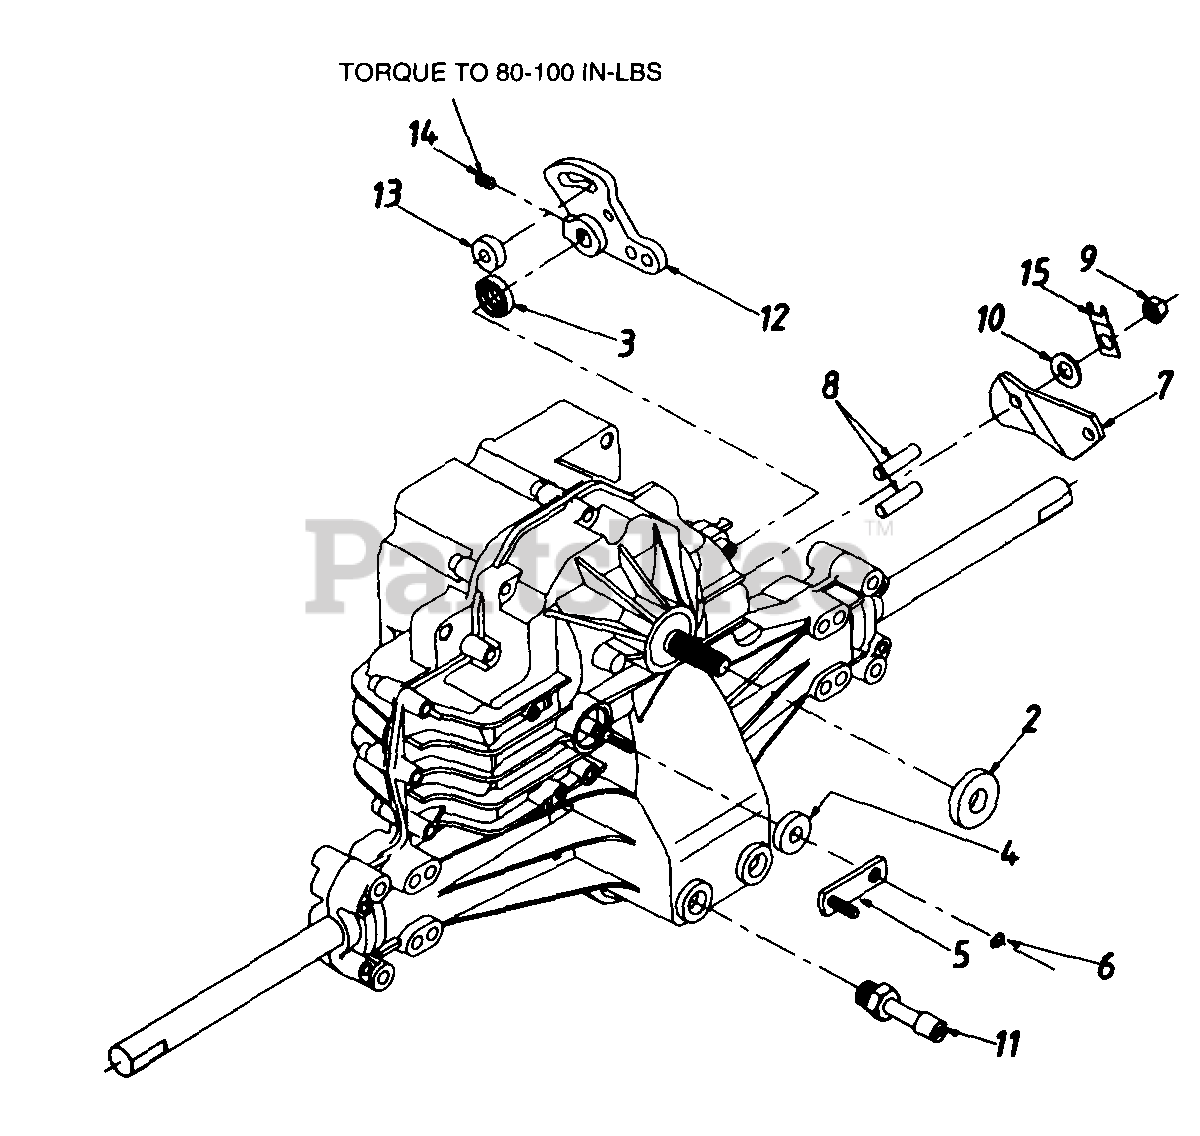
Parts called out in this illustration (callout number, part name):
2	Seal - Lip
3	Seal - Lip
4	Seal - Lip 10 X 25 X 7
5	Arm - Bypass
6	Ring - Retaining
7	Arm - Actuating
8	Pin - Actuating
9	Nut - Hex Lock 5/16-24 UNJC
10	Washer 7/16" x 7/8" x .060"
11	Breather Ass'y.
12	Arm - Control
13	Puck - Dampener
14	Set Screw
15	Strap, Locking
